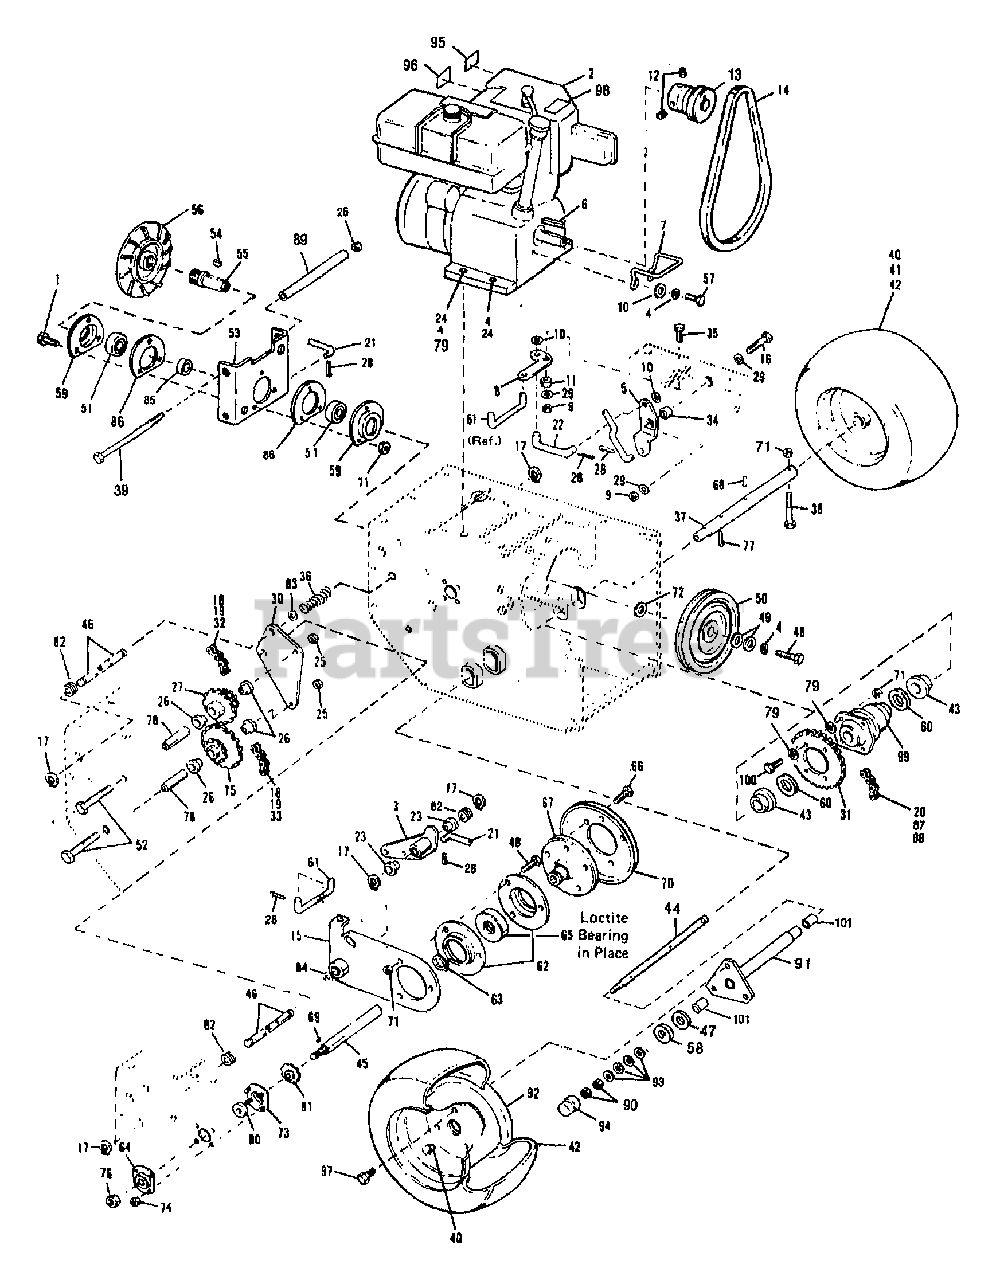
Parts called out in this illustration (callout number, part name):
1	SCR-HH 5/16-18X1.0 G5 ZP
2	TECUMSEH ENGINE HMSK80-155282L
3	ASSM-CONTROL ARM
4	WASHER-LK .312 ZP
5	ARM-CONTROL
6	KEY-.25 SQ X 1.25
7	GUIDE-BELT
8	ARM-CONTROL
9	NUT-LOCK 3/8-16
10	WASHER-FLAT 5/16 SAE
11	SPACER-PIVOT
12	SCR SET 5/16-18X.50
13	SHEAVE-ENGINE
14	BELT-V 32"
15	SUPT-DRIVE W/BEARING
16	SCR-HH 3/8-16X1.5 G5 ZP
17	RING-RETAIN .625 ID
18	LINK-OFFSET (HALF LINK)
19	LINK-CONNECTOR #41 CHAIN
20	CHAIN-DRIVE 46 P SC
21	LINK-CONTROL
22	LINK-CONTROL
23	BUSHING-FLANGE
24	SCR-HH 5/16-18X1.5 G5 ZP
25	NUT-HFLK 3/8-16 ZP
26	BEARING-FLANGE
27	ASSM-SPROCKET 9T/17T
28	PIN-COTTER .09X.75 ZP
29	WASHER-.986X.437X.083 ZP
30	PLATE-SUPPORT
31	SPROCKET-30T
32	CHAIN-DRIVE
33	CHAIN-DRIVE
34	SPACER-PIVOT
35	SCR-HH 3/8-16X1.0 G5 ZP
36	SPRING-COMPRESSION
37	SHAFT-AXLE
38	SCR-HH 5/16-18X1.75 G5ZP
39	SCR-HH 3/8-16X8.5 G5ZP
40	STEM-VALVE
41	DISC-WHEEL
42	TIRE-4.80 X 8
43	BUSHING-.875 FLNG
44	SHAFT-AXLE
45	SHAFT-HEX
46	SUPPORT-SHAFT
47	DISC-FRICTION
48	SCR-HHC 5/16-18X.75 GR 5 ZP
49	WASHER-1.25X.343X.059
50	SHEAVE-DRIVE WHEEL
51	BEARING-BALL
52	SCR-HH 3/8-16X3.5 G5 ZP
53	ASSM-DRIVE DISC WELD
54	KEY-WOODRUFF
55	SPINDLE
56	PLATE-DRIVE
57	SCR-HH 5/16-24X1.00 G5ZP
58	WASHER-D HOLE
59	RETAIN-BEARING
60	WASHER-.875
61	LINK-CONNECTING
62	RETAINER-BEARING
63	RING-SNAP
64	BEARING-FLANGE
65	BEARING-THRUST
66	SCR-HFLK 5/16-18X.50 ZP
67	HUB-FRICTION DISC
68	PIN-DRIVE
69	KEY-WOODRUFF 1/8 X 5/8
70	DISC-FRICTION
71	NUT-TOP/LK 5/16-18 ZP
72	WASHER-1.12X.759X.0329
73	ASSM-BEARING FLANGE
74	NUT-H/LK M10-24 NYLOCK
75	ASSM-SPROCKET 9T/30T
77	PIN-DRIVE .187X1.0
78	SPACER-.62X.39X2.625
79	WASHER-FLAT 5/16 SAE
80	BEARING-BALL
81	SPROCKET-9T
82	BUSHING-.68X.62X.15 FLNG
83	WASHER-1.0X.64X.029
84	WASHER-1.305X.649X.098 ZP
85	SPACER-1.0X.766X.413
86	RETAINER-BEARING
87	LINK-CONNECTOR
88	LINK-OFFSET
89	SPACER-.5X.384X7.375
90	NUT-HEX JAM 1/2-13
91	ASSM-AXLE TUBE
92	DISC-WHEEL
93	DISC-SPRING
94	CAP-DUST
95	DECAL-CHOKE
96	DECAL-PRIMER @ DEPL
97	BOLT-LUG SC
98	DECAL-WARN.HOT SURFACES
99	ASSM-DIFFERENTIAL
100	SCR-HH 5/16-18X1.25 G5ZP
101	BUSHING-NYLON
